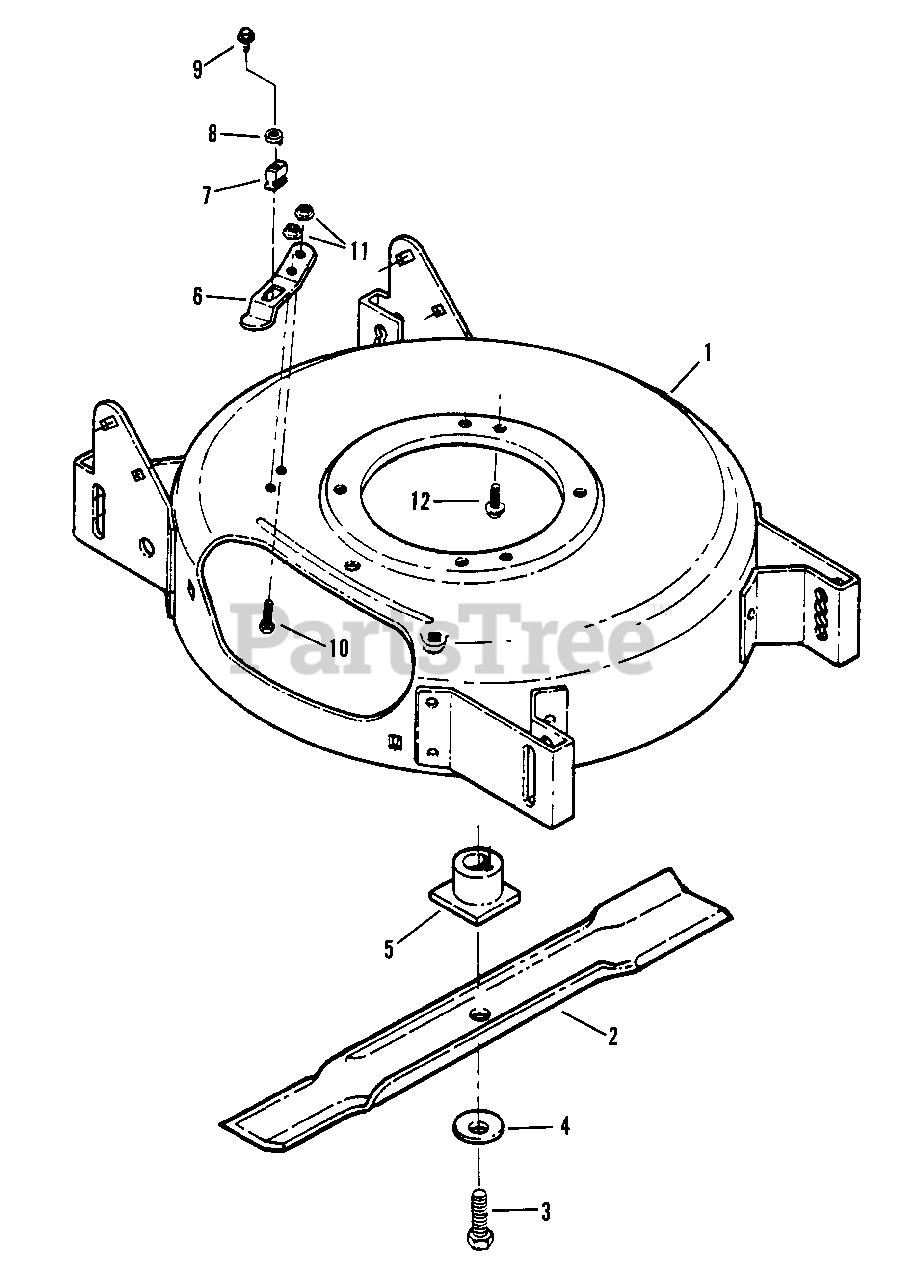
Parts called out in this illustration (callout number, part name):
1	DECK, Mower
2	BLADE, Cutter
3	SCREW, 3/8-24 x 2" Hex Head Cap (Gr. 5)
4	WASHER, Cone
5	HUB, Blade Drive (Tecumseh 2-Cycle)
6	SPRING, Interlock
7	INSULATOR, Interlock
8	WASHER, #8 Tab
9	SCREW, #8-18 x 3/4" Self-Tapping
10	SCREW, 1/4-20 x 1/2" Hex Head Cap
11	NUT, 1/4-20 Hex Flange
12	SCREW, 3/8-16 x 1" Self-Tapping
